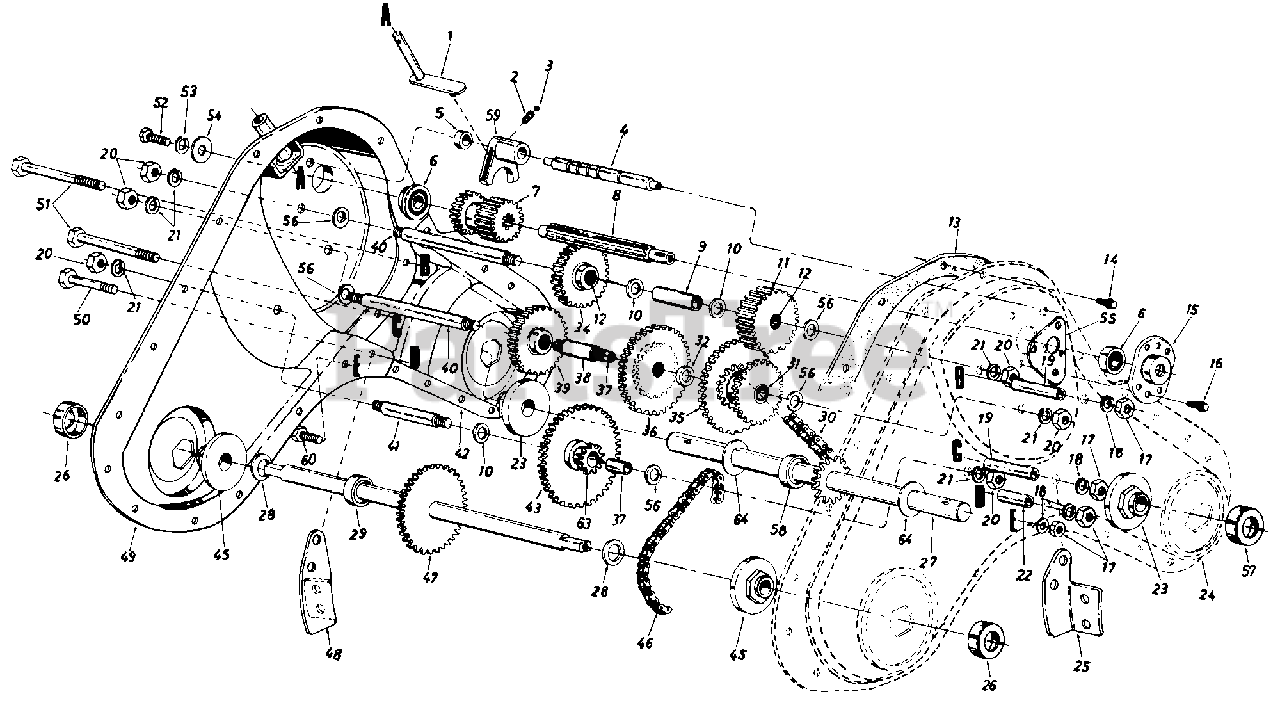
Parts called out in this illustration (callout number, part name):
1	Shifting Bracket Ass'y.
2	Compression Spring .50" Lg.
3	Ball Detent .250" Dia.
4	Detent Shaft 1/2" Dia.
5	Spacer .505" I.D. x .88" O.D.
6	Ball Brg. .62" l.D. x 1.38"
7	Spur Gear 16T (Input)
8	Input Spline Shaft 7/8n
9	Spacer .657" l.D. x 2.85" Lg.
10	Fl-Wash. .640" l.D. x 1.24"
11	Spur Gear 30T 7/8" l.D.
12	Needle Bearing 5/8" l.D.
13	Gasket-Trans. Hsg.
14	Hex Wash. S-Tap Scr. 1/4-20 x 50" Lg
15	1-3/8" Dia. Bearing Housing
16	Hex TT-Tap Scr. 1/4-20 x .75"
17	Hex Nut 5/16-18 Thd.
18	L-Wash. 5/16" l.D.
19	Spacer 1.56" Lg.
20	Hex Nut 7/16-20 Thd.
21	Bell-Wash. .45" l.D. x 1.0"
22	Spacer 1.015" Lg.
23	Tine Shaft Brg. 1.002 x 2.50
24	Trans. Housing Ass'y.-L.H.
27	Tine Shaft Ass'y. 1" O.D.
28	Fl-Wash. .75" l.D. x 1.5" O.D.
29	Spacer .75" l.D. x .50" Lg.
30	Chain #50 5/8 Pitch x 52 Links-Endless
31	Needle Bearing 5/8" l.D.
32	Fl-Wash. 5/8" l.D.
34	Spur Gear 30T 12/16" I.D.
35	30/44T Gear Ass'y. Comp.
36	Spur Gear 44T
37	Sleeve Bearing
38	Gear Hub 3/4" l.D. x 3" Lg.
39	Spur Gear 30T 1.0" l.D. x 1/2 W
40	Jack Shan 5/8" Dia. x 5"
41	Jack Shaft 5/8" Dia. x 2.38"
42	Trans. Housing Ass'y.-R.H.
43	Spur Gear 55T
45	Wheel Brg. .752" X 2.5
46	#420 Chain 1/2 Pitch x 50 Links-Endless
47	Wheel Shaft Ass'y. 15.6"
51	Hex Bolt 5/16-18 x 2.5"
52	Hex Bolt 1/4-20 x .62" Lg.
53	L-Wash. 3/8" l.D.
54	Fl-Wash. 1/4" l.D. x .93" O.D.
55	Gear Positioner Bracket
56	Fl-Wash. 7/16" l.D. x 1-3/8"
57	Dust Cover Ass'y. 1" Shan
58	Spacer 1" l.D. x 2" O.D.
59	Shifting Fork
60	Hex Bolt 5/16-18 x .75" Lg.
63	10T Sprocket Ass'y.
64	Thrust Wash. 1.03" I.D. x 1.52" O.D.
